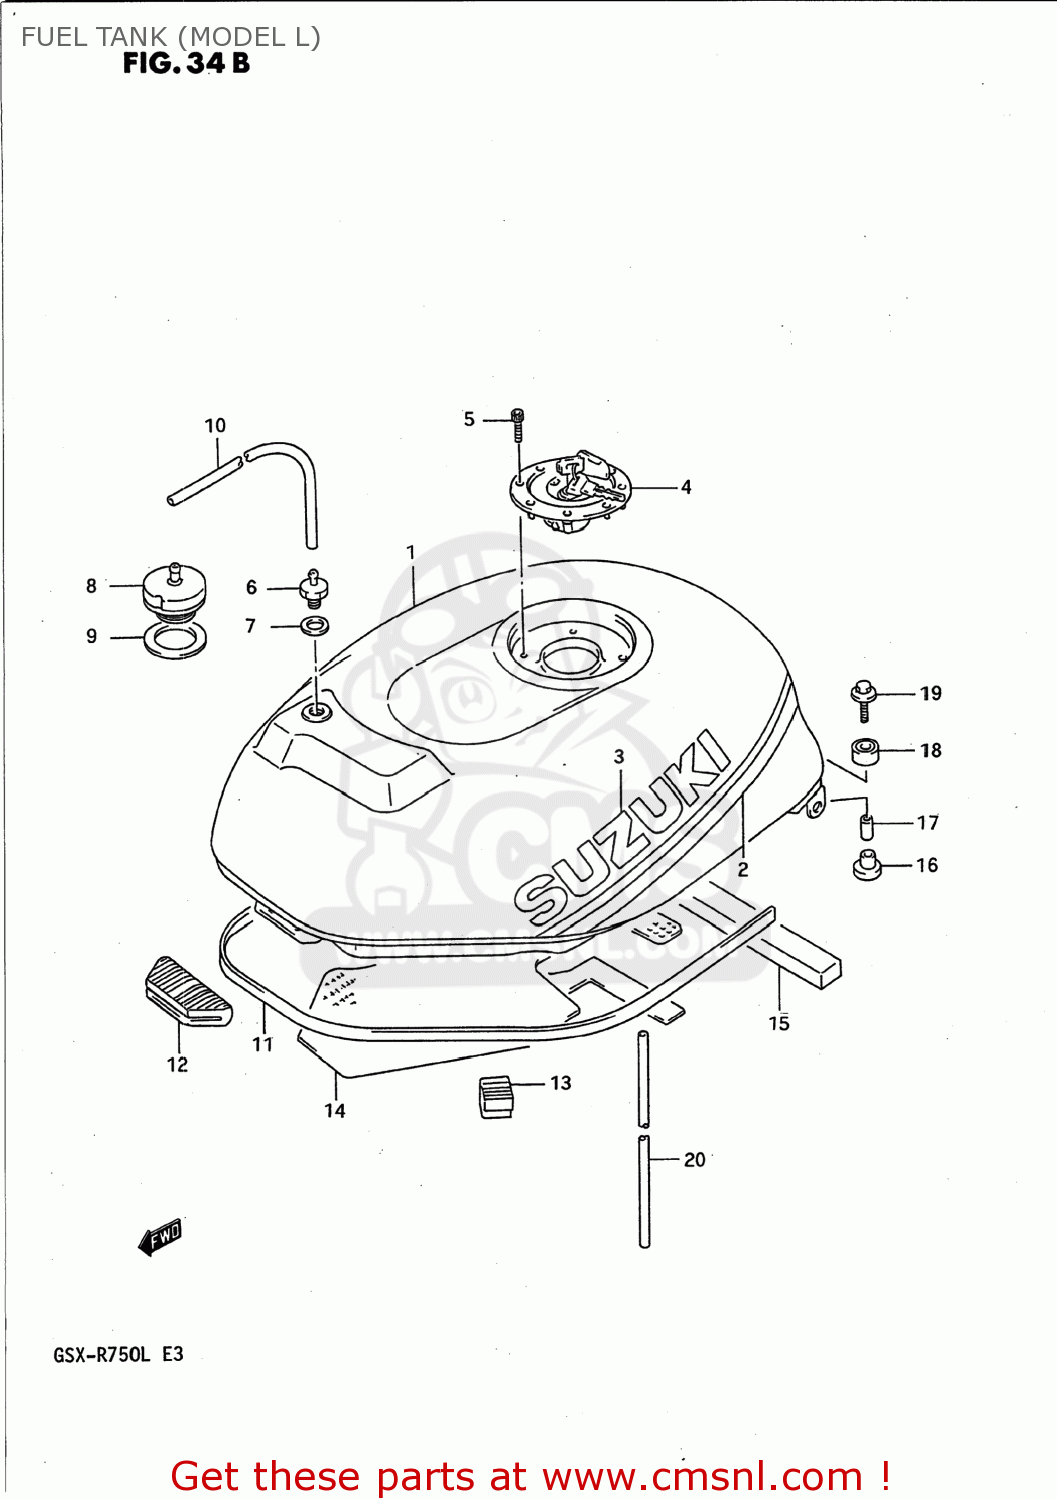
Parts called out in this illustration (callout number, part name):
1	TANK ASSEMBLY,FUEL
2	TAPE,FUEL TANK
3	EMBLEM,FUEL TANK
4	CAP SET,FUEL TANK
5	BOLT(5X20)
6	PLUG,FUEL TANK BREATHER
7	GASKET(12.5X20X2.5) (NAS)
8	(CA) VALVE,FUEL TANK BREATHER
9	GASKET 27X40X2.5 (NAS)
10	HOSE(5X8.2X600)
11	MOLDING,FUEL TANK
12	CUSHION,FUEL TANK FR
13	CUSHION,TANK,S
14	SHIELD,FUEL TANK HEAT
15	CUSHION, AIR SEAL
16	CUSHION
17	SPACER
18	CUSHION
19	BOLT(6X35)
20	HOSE
